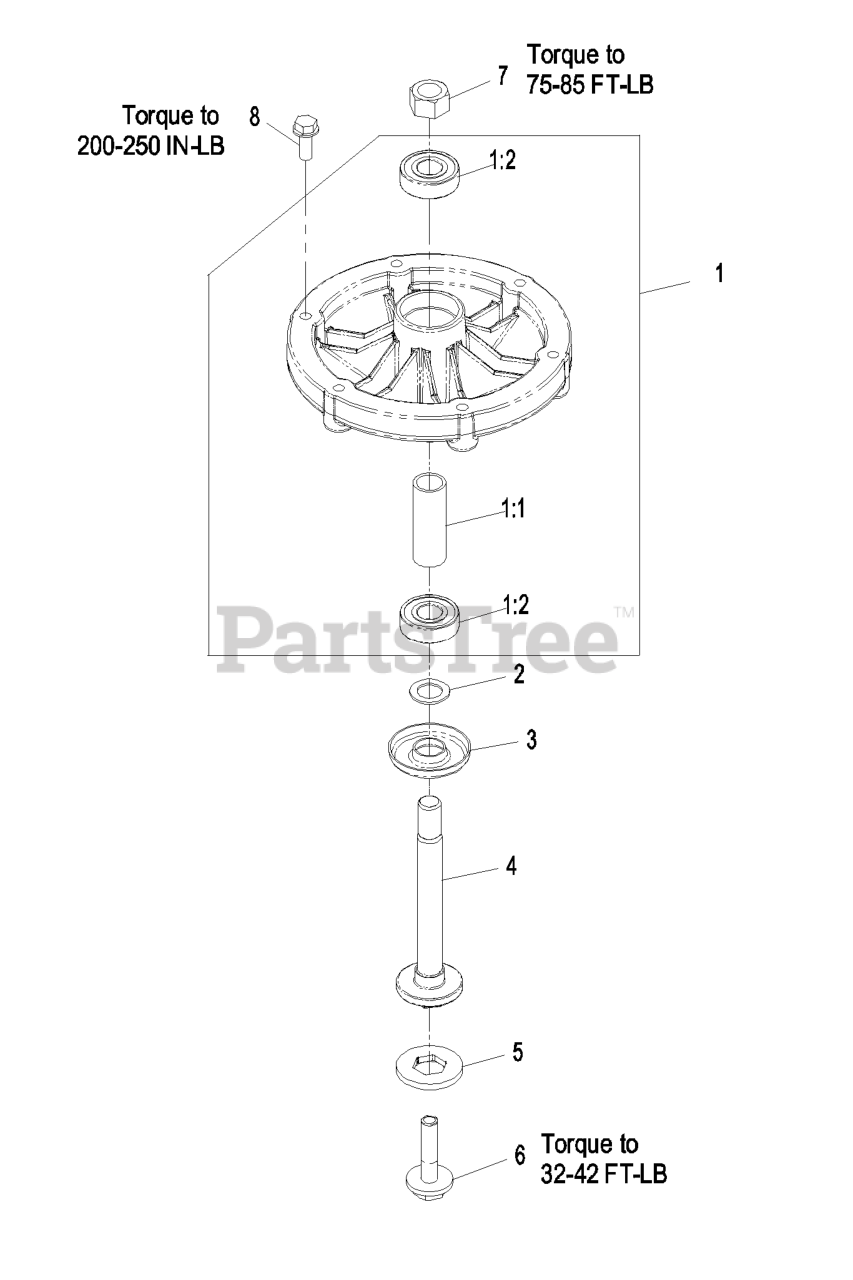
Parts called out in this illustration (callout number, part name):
1:2	BEARING-BALL
3	SHIELD-BEARING
4	SPINDLE-HEX PILOT
5	WASHER-BLADE DRIVE
6	BOLT-BLADE, SEM
7	NUT-HEX
8	SCREW-TAPTITE
